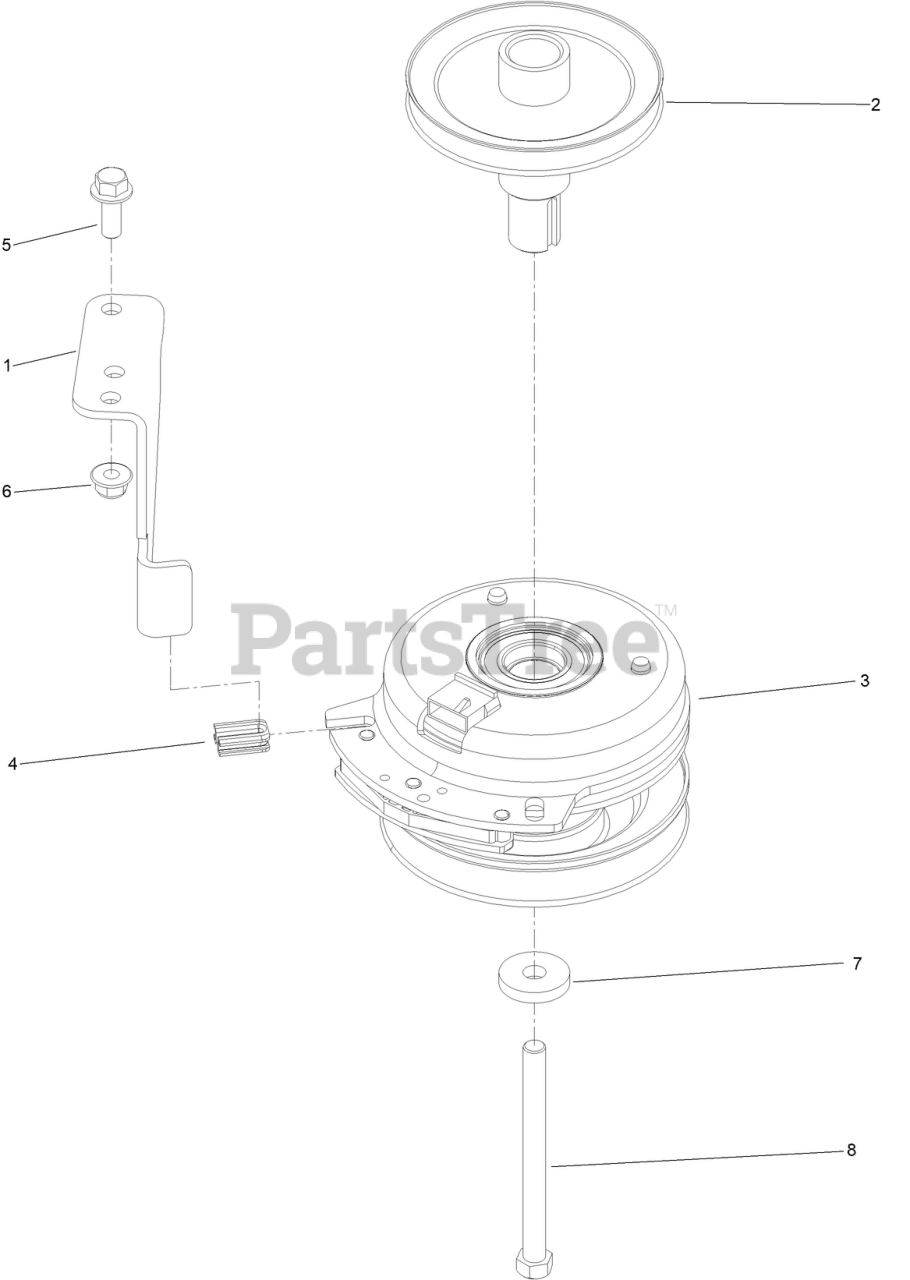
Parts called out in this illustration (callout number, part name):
1	STOP-CLUTCH (WIDE)
2	PULLEY-ENGINE
3	CLUTCH-PTO
4	ISOLATOR-CLUTCH
5	SCREW-HHF
6	NUT-HF, NI
7	WASHER
8	SCREW-HH
